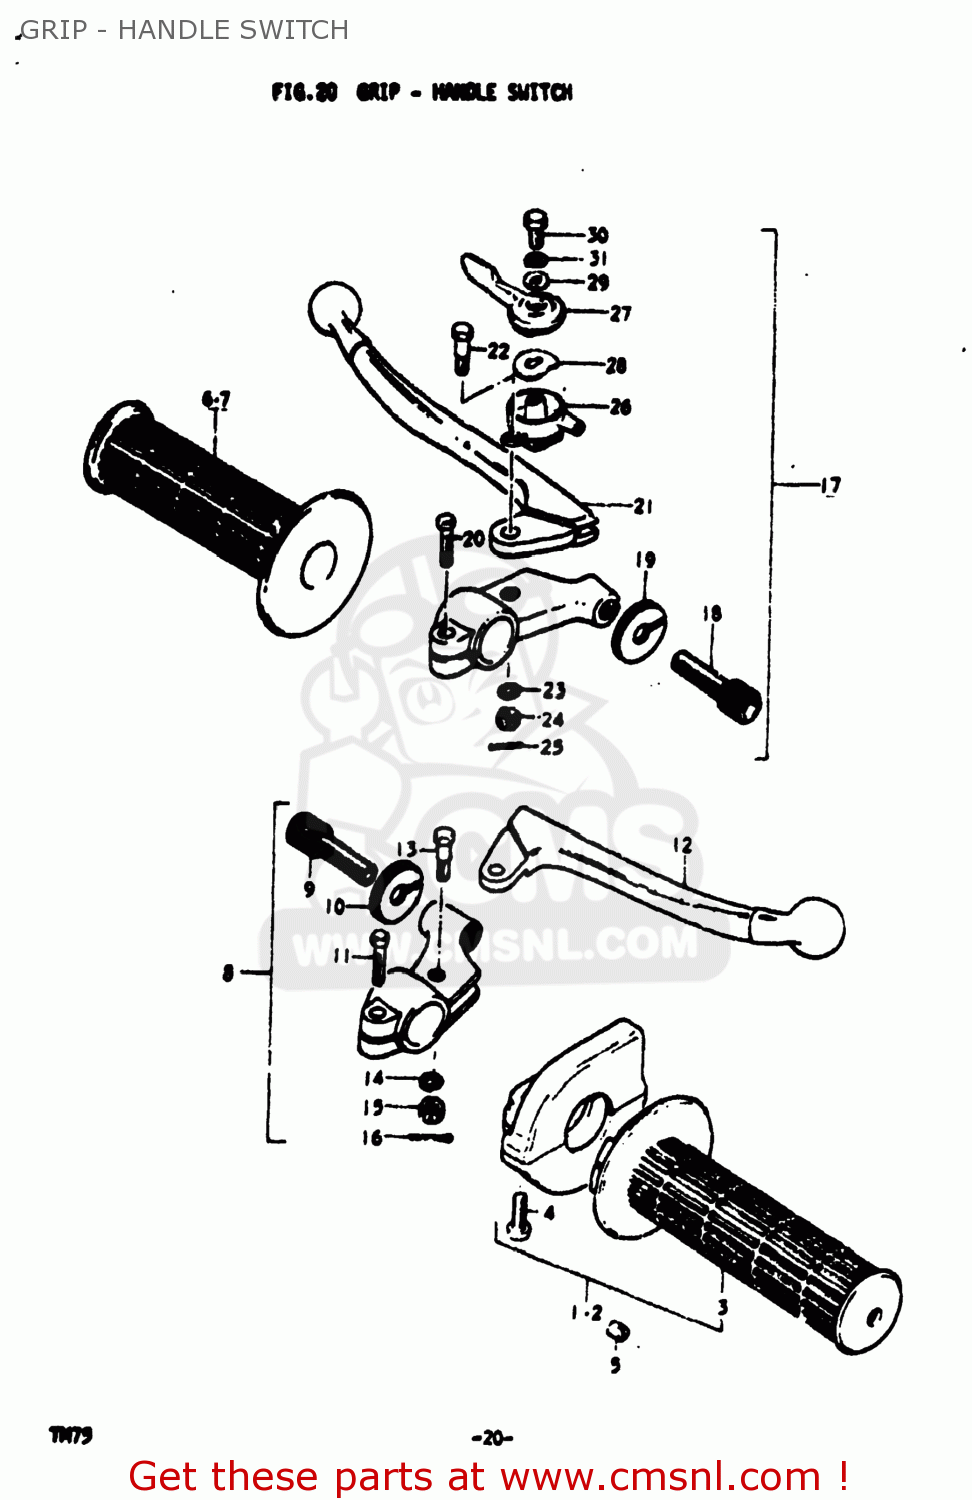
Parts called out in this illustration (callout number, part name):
1	CASE ASSEMBLY,THROTTLE
2	CASE ASSEMBLY,THROTTLE
3	GRIP,THROTTLE
4	SCREW
5	PIECE,THROTTLE END
6	GRIP,LEFT
7	GRIP,LEFT
8	LEVER ASSEMBLY,BRAKE
9	ADJUSTER,CABLE
10	NUT,CABLE ADJUSTER
11	BOLT
12	LEVER,BRAKE
13	BOLT,LEVER
14	LOCK WASHER
15	NUT,LEVER FITTNG
16	COTTER PIN
17	LEVER ASSEMBLY
18	ADJUSTER,CABLE
19	NUT,CABLE ADJUSTER
20	BOLT
21	LEVER,CLUTCH
22	BOLT,LEVER PIVOT
23	LOCK WASHER
24	NUT,LEVER FITTNG
25	COTTER PIN
26	BODY,STARTER LEVER
27	LEVER
28	WASHER,ADJUSTER
29	WASHER,STARTER LEVER
30	BOLT
31	LOCK WASHER
